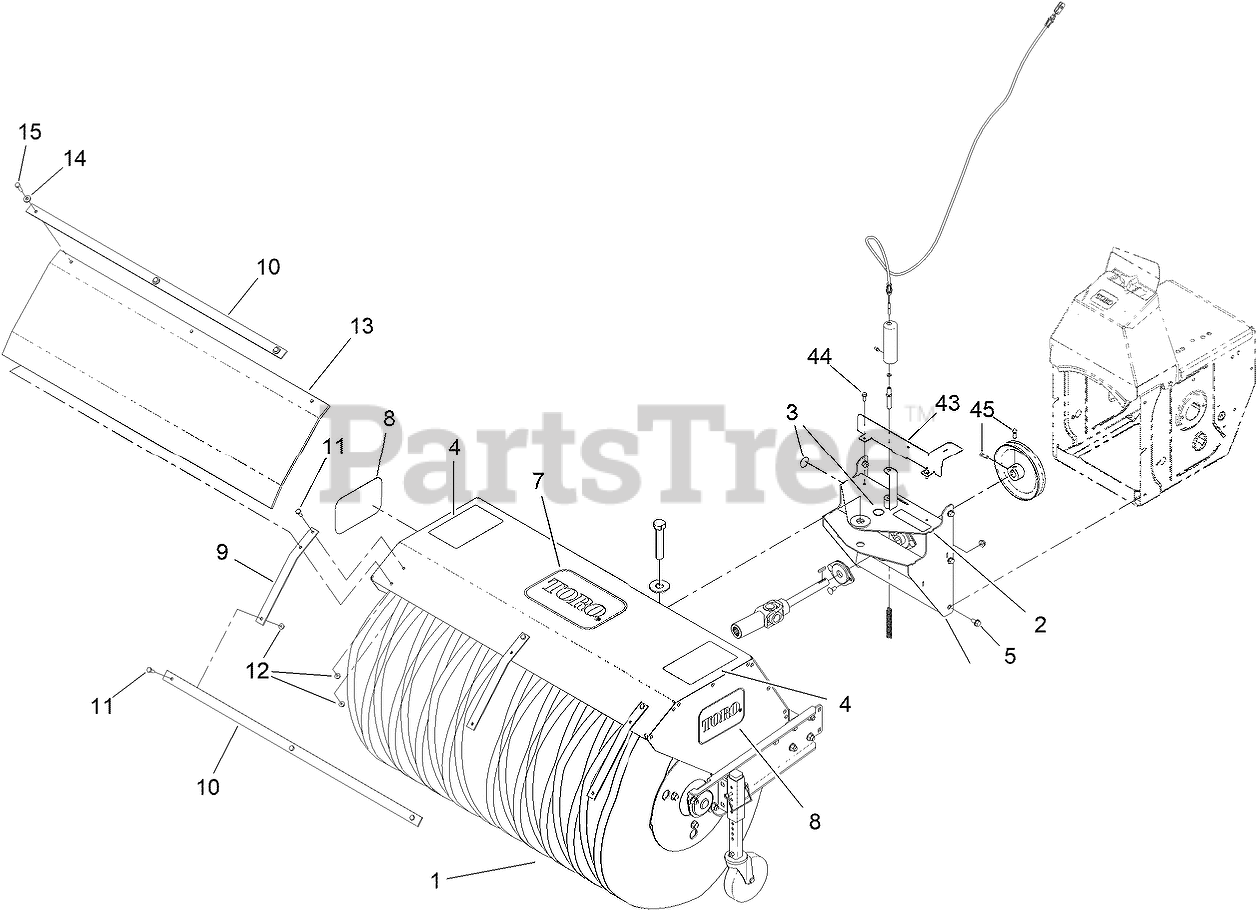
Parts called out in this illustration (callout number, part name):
1	MB BROOM-TORO
2	DECAL-COVER, MISSING
3	DECAL-GREASE
4	DECAL-WARNING
5	SCREW-HWHTF
7	DECAL
8	DECAL
9	STRAP-SUPPORT, DEFLECTOR
10	STRAP-SUPPORT, BROOM DEFLECTOR
11	SCREW-HH
12	NUT-HF
13	DEFLECTOR-BROOM
14	WASHER-FLAT
15	SCREW-HHF
43	PLATE-COVER
44	SCREW-HWH
45	SCREW-SET,SQH
